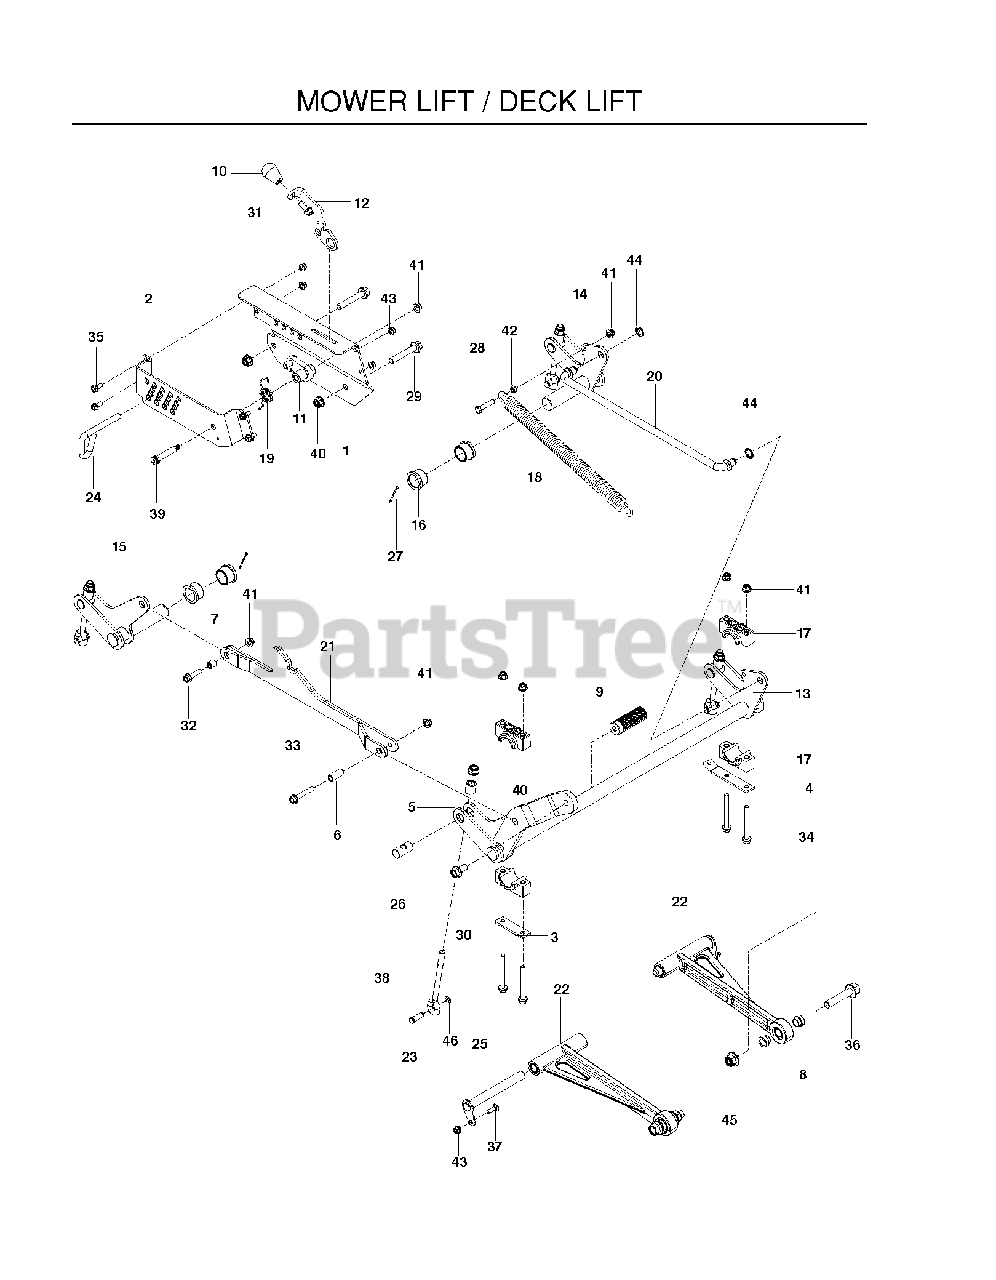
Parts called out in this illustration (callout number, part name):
1	PLATE, HEIGHT INNER ORG
2	PLATE, HEIGHT OUTER ORG
3	PLATE, PILLOW BLACK
4	PLATE, SPRING ANCHOR
5	SPACER, EYEBOLT
6	SPACER, FRONT LIFT STRAP
7	SPACER, REAR LIFT STRAP
8	SPACER, STRUT
9	PEDAL, DECK HEIGHT
10	KNOB - SHIFT
11	LATCH, TRANSPORT WLDMT
12	LEVER, TRANSPORT RELEASE
16	BUSHING, FLANGE 1.25 X 1.0
17	BLOCK, PILLOW
18	SPRING, EXTENSION
19	SPRING, TORSION
20	ROD, LIFT
21	WELDMT, DECK STRAP
22	ASSEMBLY, STRUT
23	PIN, 7/16 CLEVIS
24	PIN, HEIGHT
25	PIN, STRUT
26	PIN, TRUNION, EYEBOLT
27	COTTER PIN 1/8 X 2
28	HCS 3/8-16 X 1 3/4 GR5
29	HFFS 1/2-13 X 3 GD 5 ZD
30	HHFS 1/2-13 X 1 GR5 ZD
31	HHFS 3/8-16 X 1 GRD 5 ZD
32	HHFS 3/8-16 X 1.50 GR5 ZD
33	HHFS 3/8-16 X 2-1/4 GR 5 ZD
34	HHFS 3/8-16 X 3.5 GD 5 ZD
35	HHFS 5/16-18 X 3/4
36	HHFS 5/8-11 X 3.0 GD 8 ZD
37	RHSNB 5/16C X 1
38	EYEBOLT, DECK LIFT
39	BOLT, SHOULDER, 1/2 X 2.25
40	NUT, 1/2-13 HEX FLG NYLOC ZD
41	NUT 3/8-16 HEX FLG NYLOC ZD
42	NUT 3/8-16 HEX JAM
43	5/16-18 NYLOC FLANGE NUT
44	NUT 5/8 PUSH
45	NUT 5/8-11 FLG NYLOC ZD
46	RING, E, 7/16
